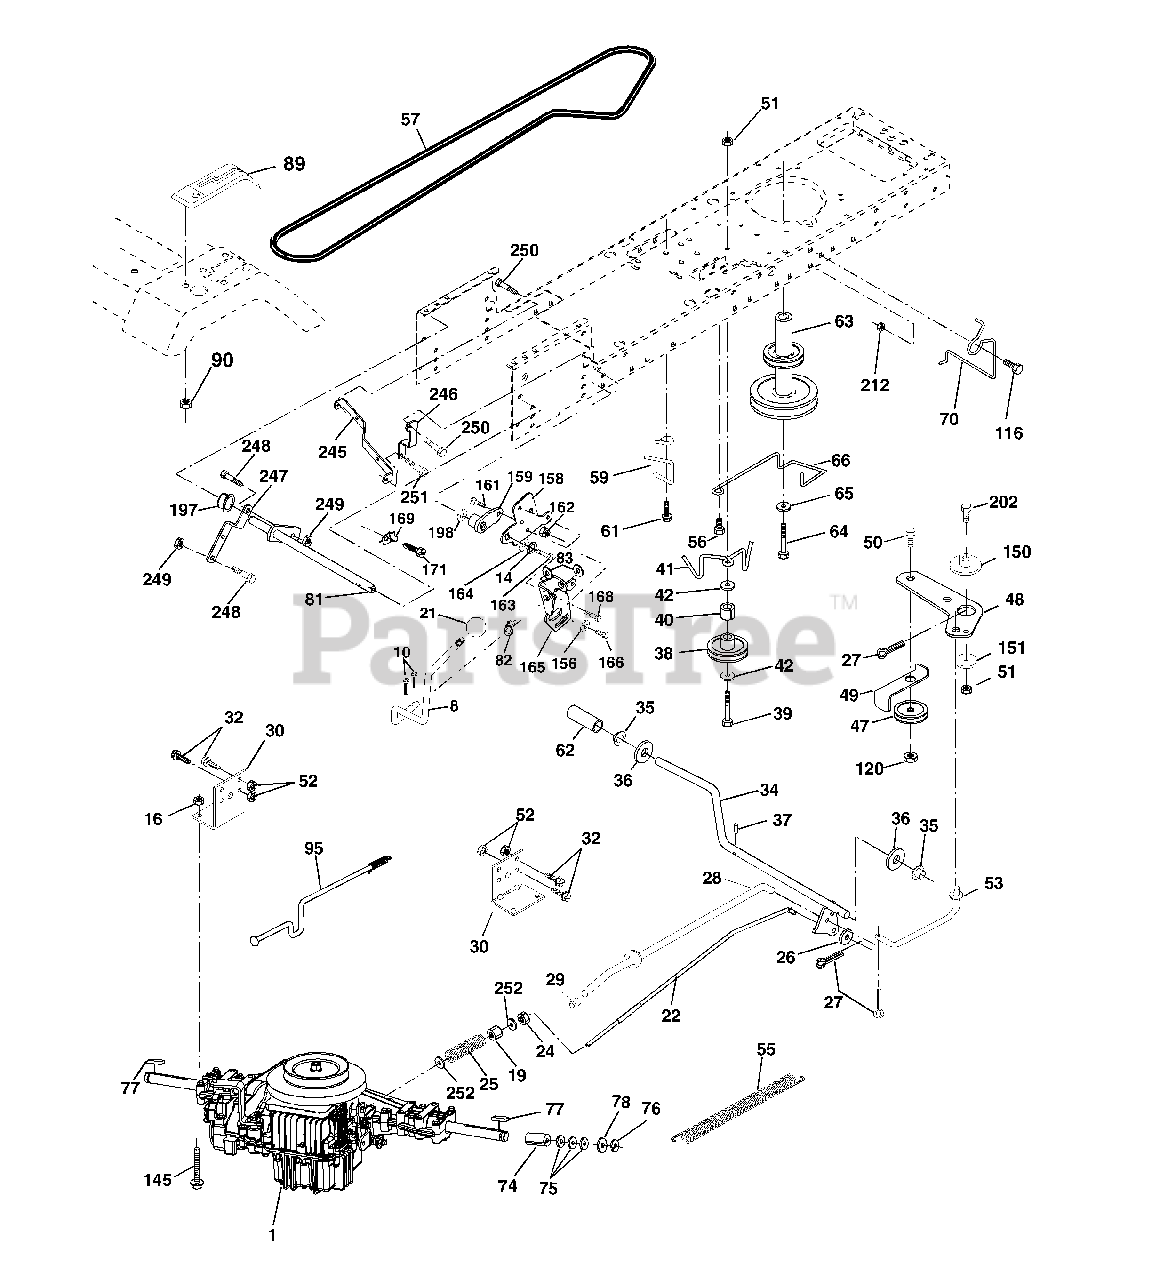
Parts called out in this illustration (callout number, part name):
8	Rod Shift Fender Adjust LT
10	Pin Cotter 1/8 x 1 CAD
14	Washer Lock Hvy Helical
16	Nut Lock Hex W/Ins 5/16-18 Unc P
19	Nut Lock Hex W/Wsh 3/8-16 Unc
21	Knob, Round 1/2-13
22	Rod, Brake
24	Nut
25	Spring, Brake Rod
26	Washer
27	Pin Cotter 1/8 x 3/4 CAD.
28	Rod, Parking Brake
29	Cap, Parking Brake
30	Bracket, Transaxle
32	Bolt Hex Hd 5/16-18 Unc x 3/4
34	Shaft, Foot Pedal
35	Bearing, Nylon
36	Washer
37	Pin, Roll
38	Pulley, Idler, Flat
39	Bolt
40	Spacer, Split
41	Keeper, Belt Idler
42	Washer 13/32 x 13/16 x 12 Gauge
47	Pulley, Idler, V-Groove
48	Bellcrank Clutch Grd Drv Stl
49	Retainer, Belt
50	Bolt
51	Nut Crownlock 3/8-16 UNC
52	Nut Crownlock 5/16-18 UNC
53	Link, Clutch
55	Spring, Return, Clutch
56	Screw 3/8-16 x 1
57	V-Belt, Ground Drive
59	Keeper, Center Span
61	Screw 3/8-16 x 3/4
62	Cover, Pedal
63	Pulley, Engine
64	Bolt, Hex
65	Washer
66	Keeper Belt Engine Hydro
69	Screw
70	Keeper Belt Engine
74	Spacer, Axle
75	Washer 25/32 x 1-1/4 x 16 Gauge
76	E-Ring
77	Key, Square
78	Washer 25/32 x 1-5/8 x 16 Gauge
81	Shaft Asm Cross
82	Spring Torsion T/A
83	Washer 17/32 x 3/4 x 16 Ga.
89	Console, Hydro
90	Screw Hex Wsh 1/4-20
95	Rod Bypass
116	Bolt Rdhd Sq Neck 3/8-16 x 1.00
120	Nut Lock Flg. 3/8-16 Unc
145	Bolt Hex Flghd 5/16-18 x Gr. 5
150	Spacer Retainer
151	Washer 13/32 x 2 x 10 Ga.
156	Washer Srrted 5/16 ID x 1.125
158	Bracket Shift Mount
159	Hub Tapered Flange Shift LT
161	Bolt Rdhd Sqnk 1/4-20 x 3/4 Gr. 5
162	Nut Crownlock 1/4-20 Unc
163	Bolt Hex Fin 1/4-20 Unc x 1 Gr. 5
164	Washer 5/8 x .281 x 10 Ga.
165	Bracket Pivot Lever
166	Screw 5/16-18 x 5/8
168	Bolt Shoulder 5/16-18 x .561
169	Plate Fastening LT
171	Screw Thdrol 3/8-16 x 1/2 TY-TT
197	Nyliner Snap-In 5/8" Id
198	Washer Nyl 7/8 Id x .105
202	Bolt Carr Sh 3/8-16 x 1-3/4 Gr. 5
212	Nut Hex Flange Lock
245	Strap Torque LH
246	Strap Torque RH
247	Link, Transaxle
248	Bolt Shoulder
249	Nut Lock 5/16-18 NC THD
250	Screw 3/8-16
251	Screw 5/16-18 x 1
252	Washer 13/32 x 1 x 16 Ga.
